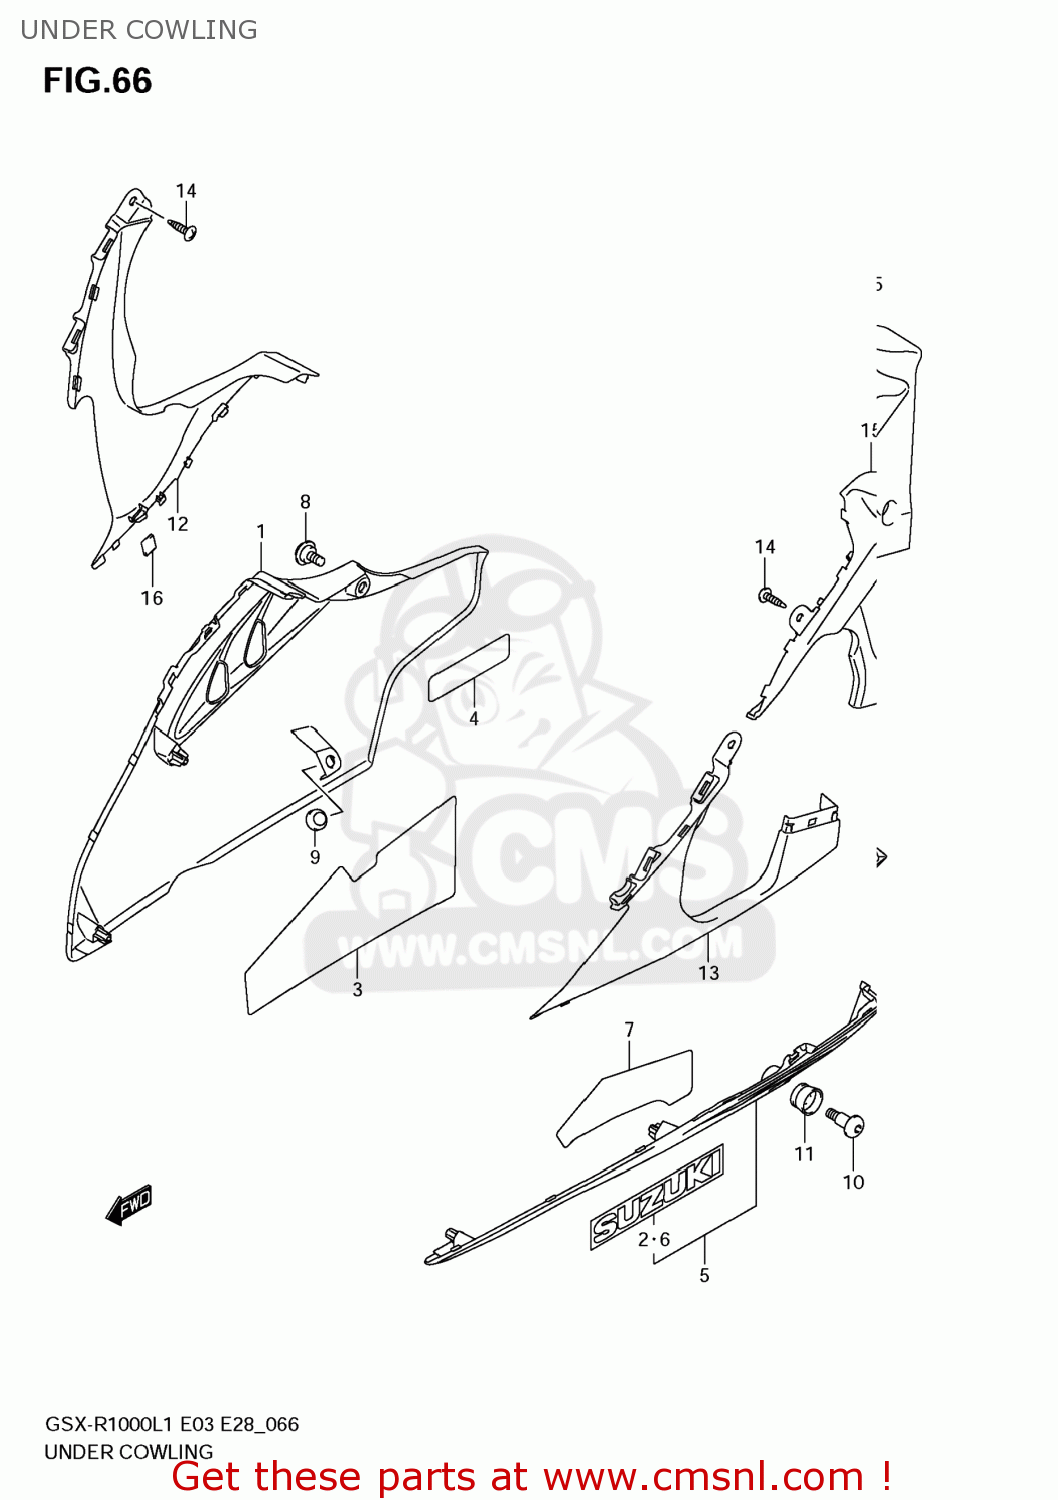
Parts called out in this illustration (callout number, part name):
1	COWLING,UNDER,R(BLUE)
2	EMBLEM,SUZUKI
3	SHIELD,UNDER COWL HEAT,R
4	SHIELD,HEAT
5	COWLING,UNDER,L(BLUE)
6	EMBLEM,SUZUKI,L
7	SHIELD,UNDER COWL HEAT,L
8	SCREW(5X13)
9	CUSHION
10	SCREW(6X20)
11	CUSHION,UNDER COWLING,L
12	COWLING,SIDE LWR,R
13	COWLING,SIDE LWR,L
14	SCREW
15	COVER,SIDE COWL,L
16	CUSHION,RR COVER NO.2
